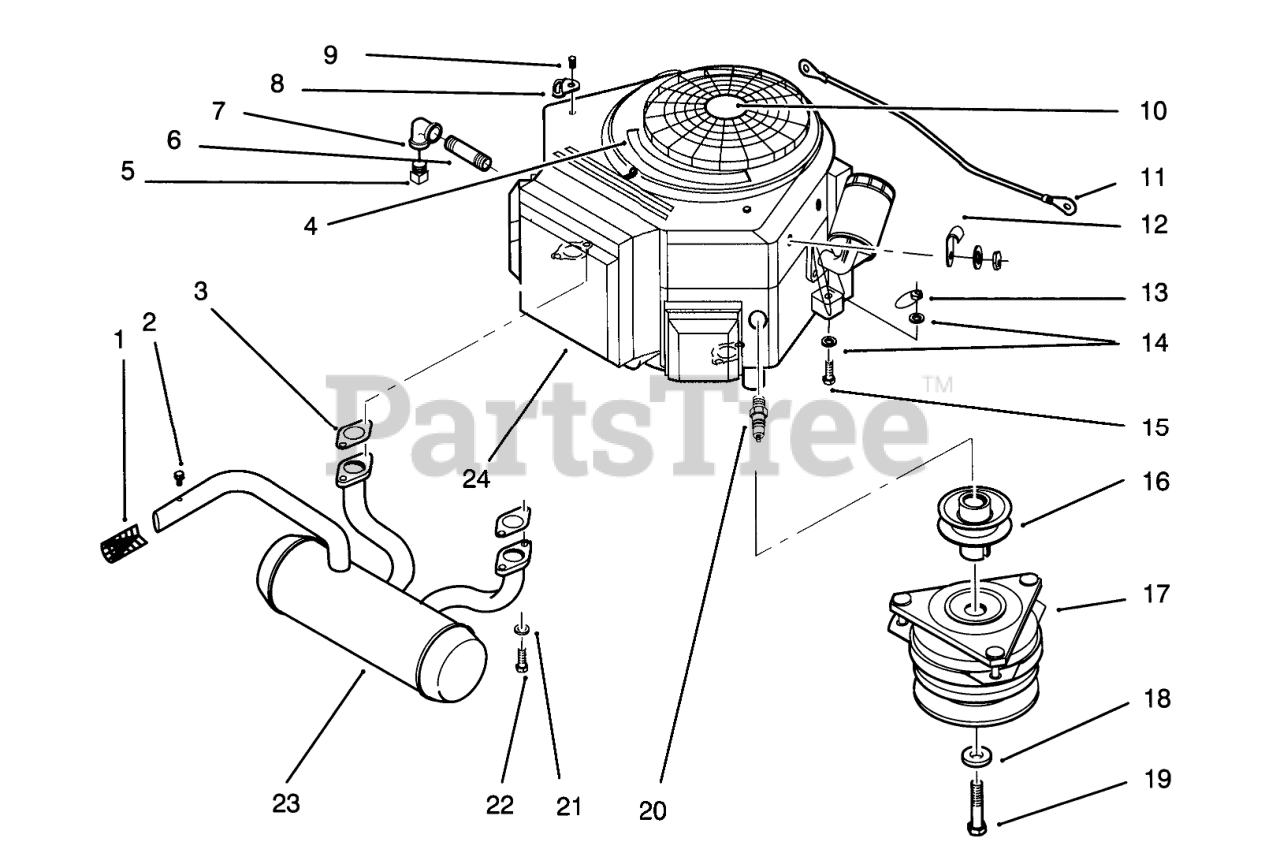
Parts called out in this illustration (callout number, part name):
1	Arrester-Spark
2	BOLT-HEX S.T. #8X1/2
3	GASKET-MUFFLER
4	DECAL - POWER PLUS
5	PLUG-PIPE, SQH
6	NIPPLE-PIPE
7	ELBOW 3/8 90 DEG
8	CLEVIS
9	Screw
10	DECAL-TORO ENGINE
11	Wire-Starter to Solenoid
12	J-CLIP
13	NUT-LOCK, NI
14	WASHER-PLAIN
15	SCREW-HH
16	PULLEY-ENGINE HYD R
17	Clutch
18	WASHER
19	SCREW-HH
20	SPARK PLUG
21	WASHER-LOCK
22	SHCS 5/16-18X.625
23	MUFFLER
24	Engine
